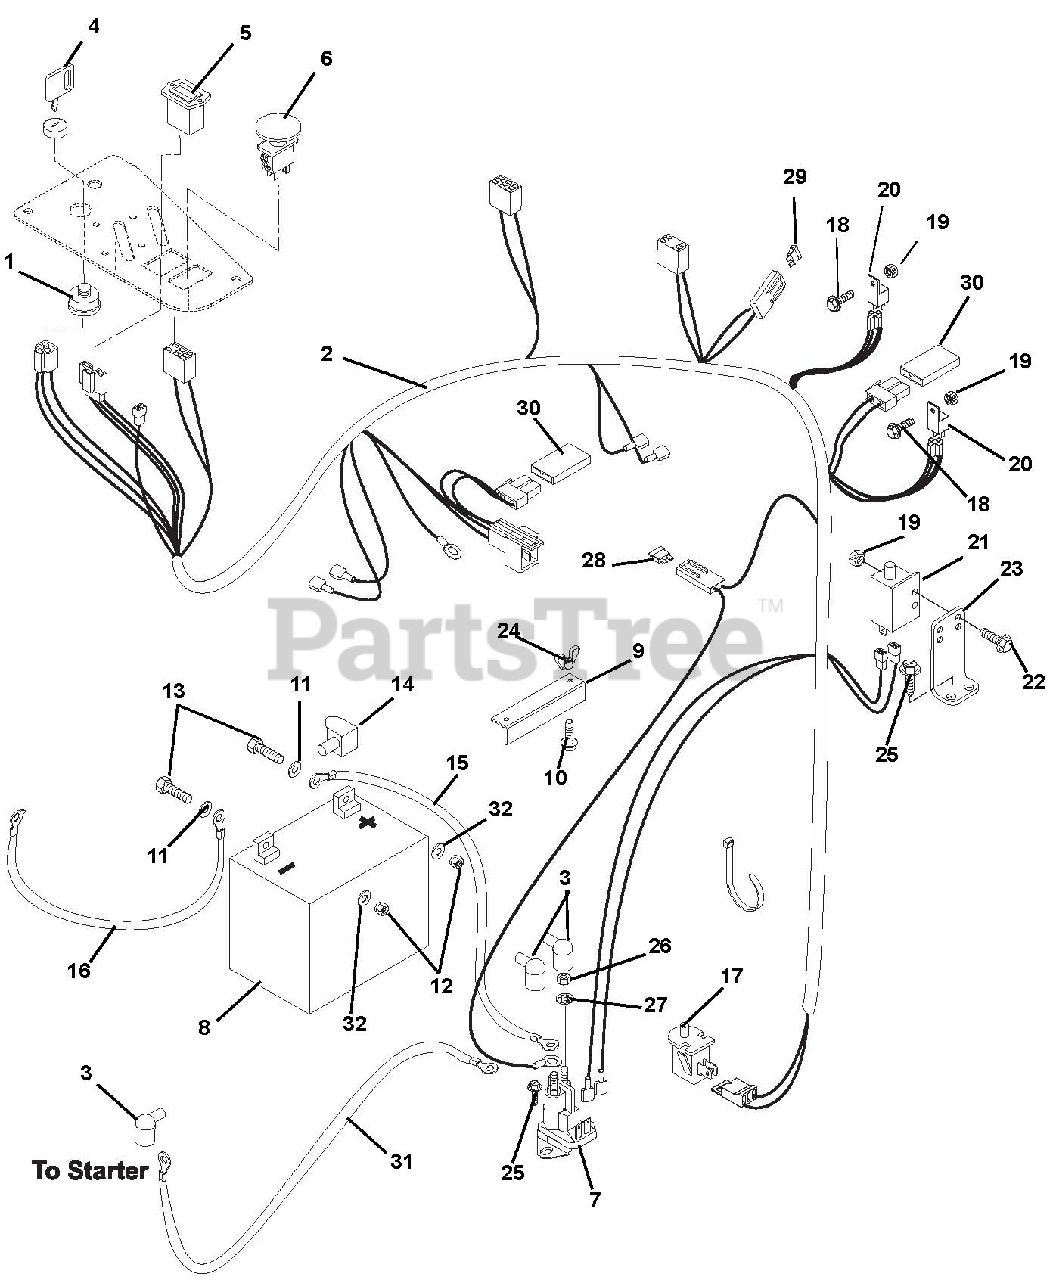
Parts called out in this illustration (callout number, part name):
1	Key Switch
2	Harness, Wiring IZ/CZ 6-Pin
3	Boot, Eyelet Terminal
4	Key with Shield
5	Hour Meter
6	Switch, Clutch With Retainer Ring
7	Solenoid
9	Hold Down
10	Bolt, Round Head Square Neck .25-20 x 7.50
11	Washer, Flat Steel .281 x .620 x .065
12	Nut, Hex .25-20
13	Bolt, Hex .25-20 x .75 Grade 5
14	Insulator
15	Cable, Positive Battery 9.00"
16	Ground Cable
17	Switch, Snap Mounting (N.O.)
18	Screw, Machine 10-24 x .50 Hex Washer Head
19	Nut, Locking Nylon 10-24 With Insert
20	Relay
21	Switch, Single Pole
22	Screw, Machine 10-24 x .75 Hex Washer Head
23	Mount, Brake Switch
24	Nut, Locking Wing .25-20
25	Screw, Tapping .25-20 x .50 Hex Washer Head
26	Nut, Jam .31-24
27	Washer, Locking .31 x .078 Regular
28	Fuse, 25 Amp
29	Fuse, 20 Amp
30	Diode, Connector Shell
31	Cable, Starter
32	Washer, Lock .25 x .062
